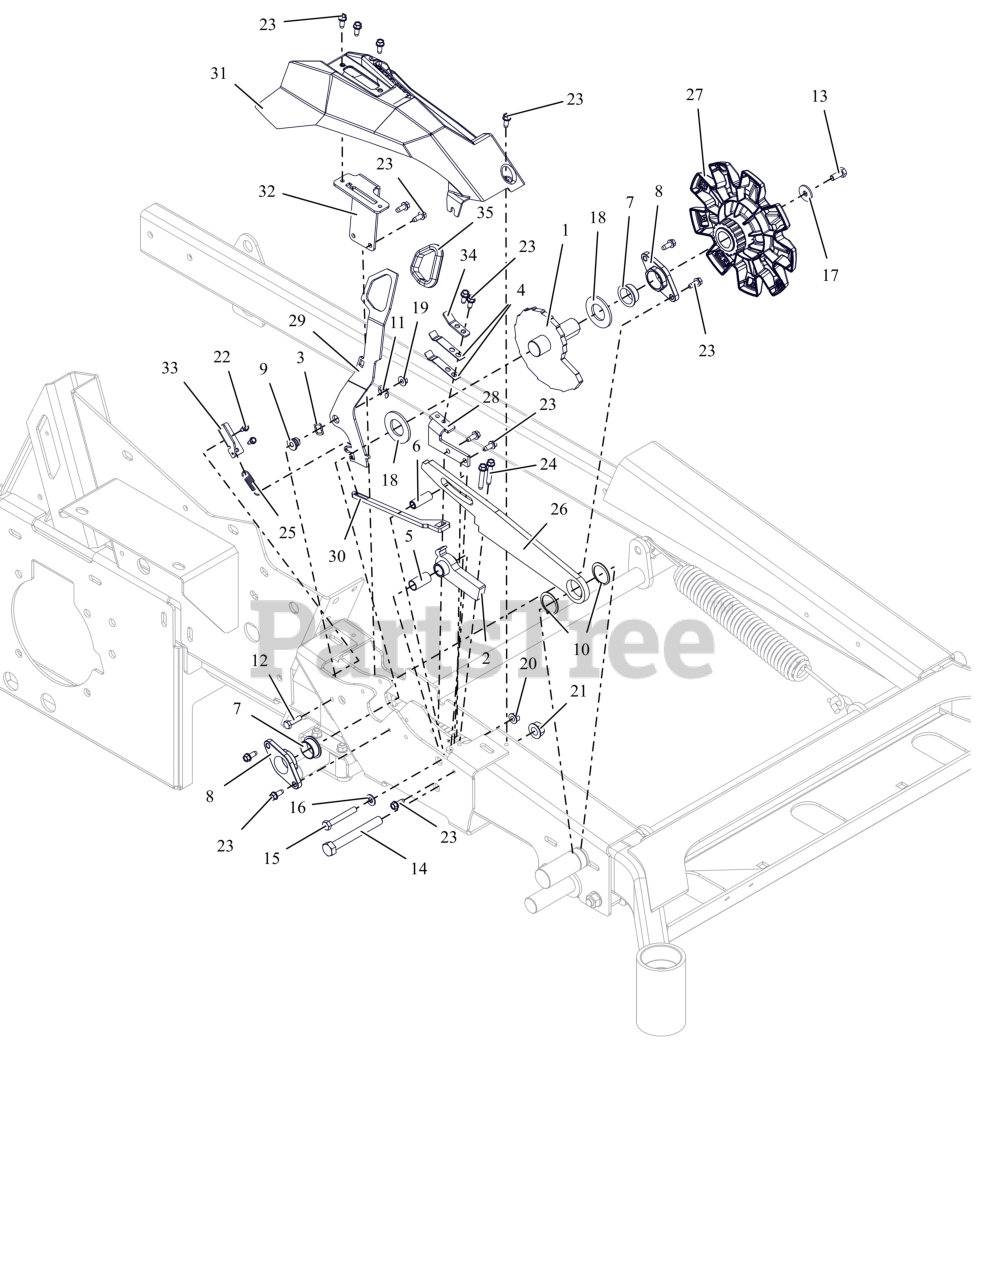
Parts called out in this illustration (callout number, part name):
1	WLDMT, HOC
2	ARM, TRANSPORT LOCK
3	WAVE WASHER .531X.781X.125FH
4	ARM, HOC DETENT
5	SPCR-SLV .531 X .625 X 1.25
6	SPCR, SLV .328 X .439 X 1.381
7	BSHG-FLG 1.0X1.125X.50X1.375 R
8	BSHG, 1.000X1.375X.650
9	BSHG FLANGED .270 X .500 X .468 X .75
10	RG-RET-EXT 1.25 X .050
11	RG-RTNG-EXT .500X.042 (E)
12	BLT,HEX .25-20X1.00 G5 ZCC
13	BLT,HEX .31-18X.75 G5 ZCC
14	BLT, HEX .50-13X4.00 G5 ZCC
15	BLT, HEX .31-18X2.25 G5 ZCC
16	WSHR,FLT .344X.688X.065 ZCC
17	WSHR,FLT .328X1.00X.094 ZCC
18	WSHR-FL-STL 1.062X2X0.134 ZCC
19	NUT-LK-CTR-FLG .25-20 ZC120
20	NUT,LK-CTR-FLG .31-18 GF ZCC
21	NUT-LK-CTR-FLG .500-13 GG ZCC
22	SCR,TAP #10-24X.50 HWH TR ZCC
23	SCR,TAP .25-20X.625 HWH ZCC
24	SCR-TAP .25-20X1.50 HWH ZCC
25	SG-TENS .063X.44X1.56
26	ARM, HOC LINK (BLACK)
27	WHEEL, HOC INDEX
28	BRKT, HOC DETENT MTG (BLACK)
29	LEVER, TRANSPORT LOCK (BLACK)
30	ARM, TRANSPORT LOCK (BLACK)
31	COVER, TRANSPORT LOCK
32	PLATE, TRANSPORT LOCK POSITION (BLACK)
33	BRKT, SPRG (BLACK)
34	TAB, REINFORCING (BLACK)
35	GROMMET 1.70ID X 2.0OD
